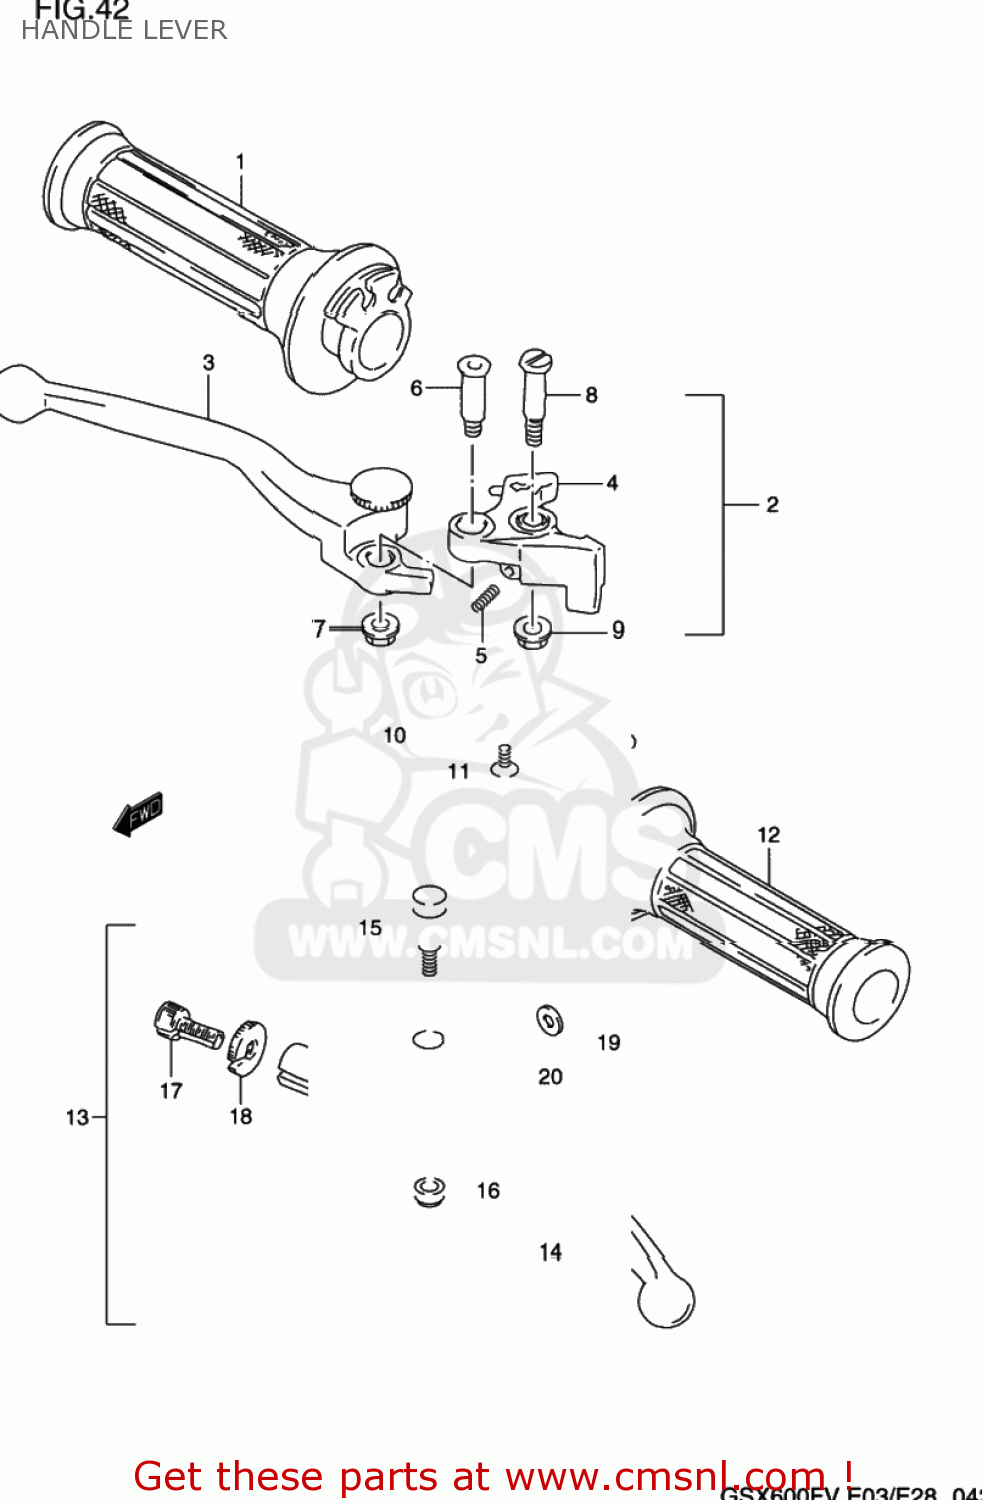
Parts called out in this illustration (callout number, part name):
1	GRIP,THROTTLE
2	LEVER ASSEMBLY,BRAKE
3	LEVER,ADJUST
4	KNOCKER
5	SPRING
6	BOLT,LEVER
7	NUT
8	BOLT,LEVER PIVOT
9	NUT
10	SWITCH ASSEMBLY,STOP
11	SCREW
12	GRIP,L
13	LEVER ASSY,CLUTCH
14	LEVER,CLUTCH
15	BOLT,LEVER PIVOT
16	NUT
17	ADJUSTER,CABLE
18	NUT,CABLE ADJUSTER LOCK
19	BOLT
20	WASHER
